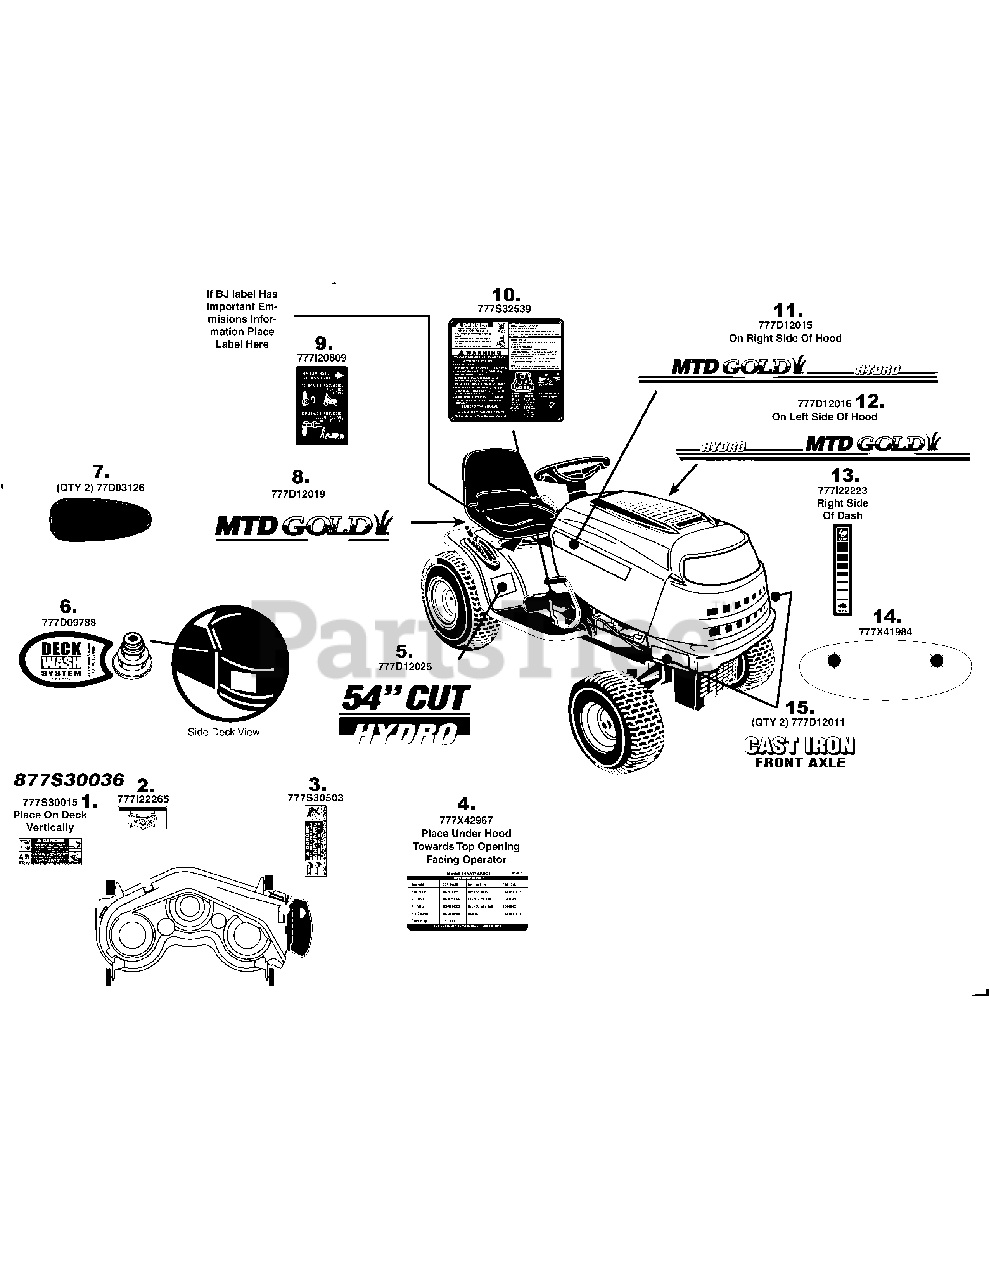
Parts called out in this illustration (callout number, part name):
1	LBL.RIDER DNGR.STRAIGT
2	LABEL-BELT ROUTE
3	LABEL-DANGER CHUTE
4	LABEL:RIDER:PARTS: A815K
5	LABEL:RIDER:SD FENDER:54" HYDRO
6	LABEL:RIDER:WHITE
7	LABEL-REFLECTOR FNDR
8	LABEL-RIDER REAR FENDER MTD GOLD
9	LABEL-HITCHPLATE
10	LABEL:RIDER:SAFETY HYDRO
11	LABEL-RIDER HOOD MTD GOLD HYDRO RH
12	LABEL-RIDER HOOD MTD GOLD HYDRO LH
13	LABEL-DASH RH
14	LABEL:RIDER 1&5 STYLE GRILL
15	LABEL-RIDER LOWER GRILLE CAST IRON
